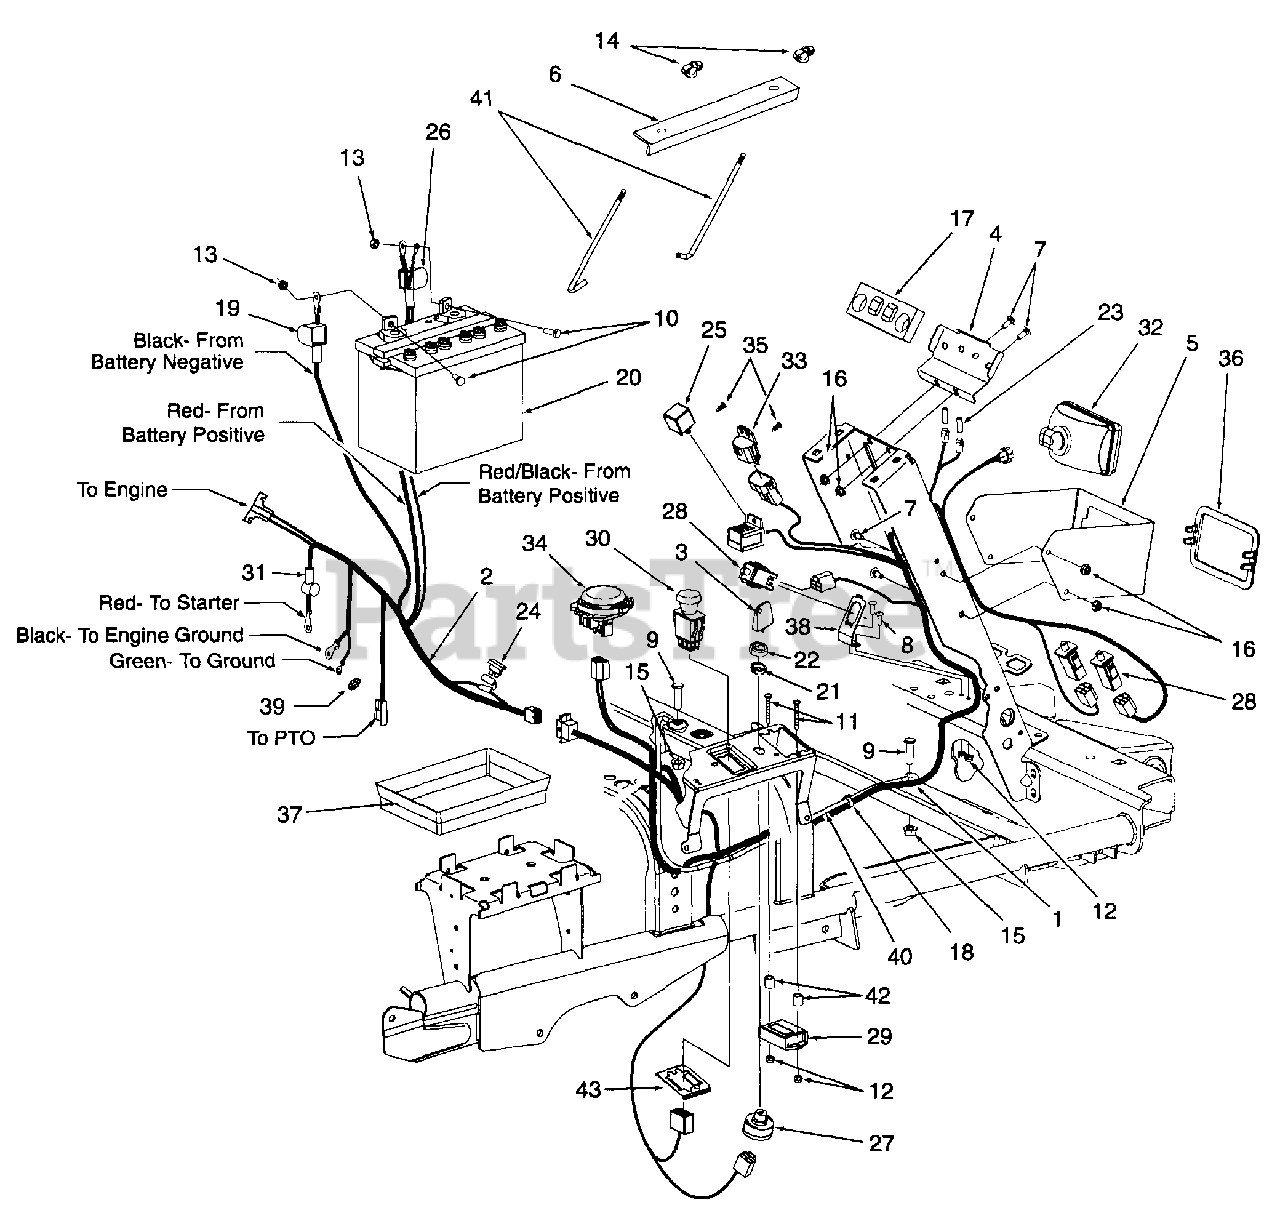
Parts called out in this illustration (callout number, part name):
1	Wire Harness, Main
2	Wire Harness, Engine
3	Key, Ignition
7	Bolt, Carriage, 1/4-20 x .62
8	Screw, Machine, #10-24 x 5/8
9	Screw, Hex Cap, 3.8-16 x 1.25
10	Screw, Hex Cap, 1/4-20 x .75 GR5
11	Screw, Pan Hd Cutting, #10-24
12	Nut, Hex Insert Lock, #10-24
13	Nut, Hex Sems, 1/4-20
14	Nut, Nylon Wing, 1/4-20
15	Nut, Hex Flange Lock, 3/8-16
16	Nut, Hex Flange Lock, 1/4-20
17	Foam Protector, Indicator Light
18	Cable Tie
19	Cover, Battery Terminal - Black
21	Nut, Ignition Switch, 5/8-32
22	Cap, Ignition Switch
23	Bulb, Indicator
24	Fuse, Mini, 20Amp
25	Relay
26	Cover, Battery Terminal - Red
27	Switch, Ignition
28	Switch, Plunger Safety
29	Hourmeter/Tachometer
30	Switch, PTO
31	Cover, Terminal - Red
32	Headlight Assembly
33	Sensor, Voltage
34	Switch, Seat
35	Retainer, Ratchet
36	Bezel, Headlight
37	Tray, Battery
38	Spring, Switch Mounting
39	Washer, External Lock, 5/16
40	Rod, Harness Mtg
41	Rod, Battery Retainer
42	Spacer, .315 x .50 x .52
43	Bracket, PTO Switch Retainer
